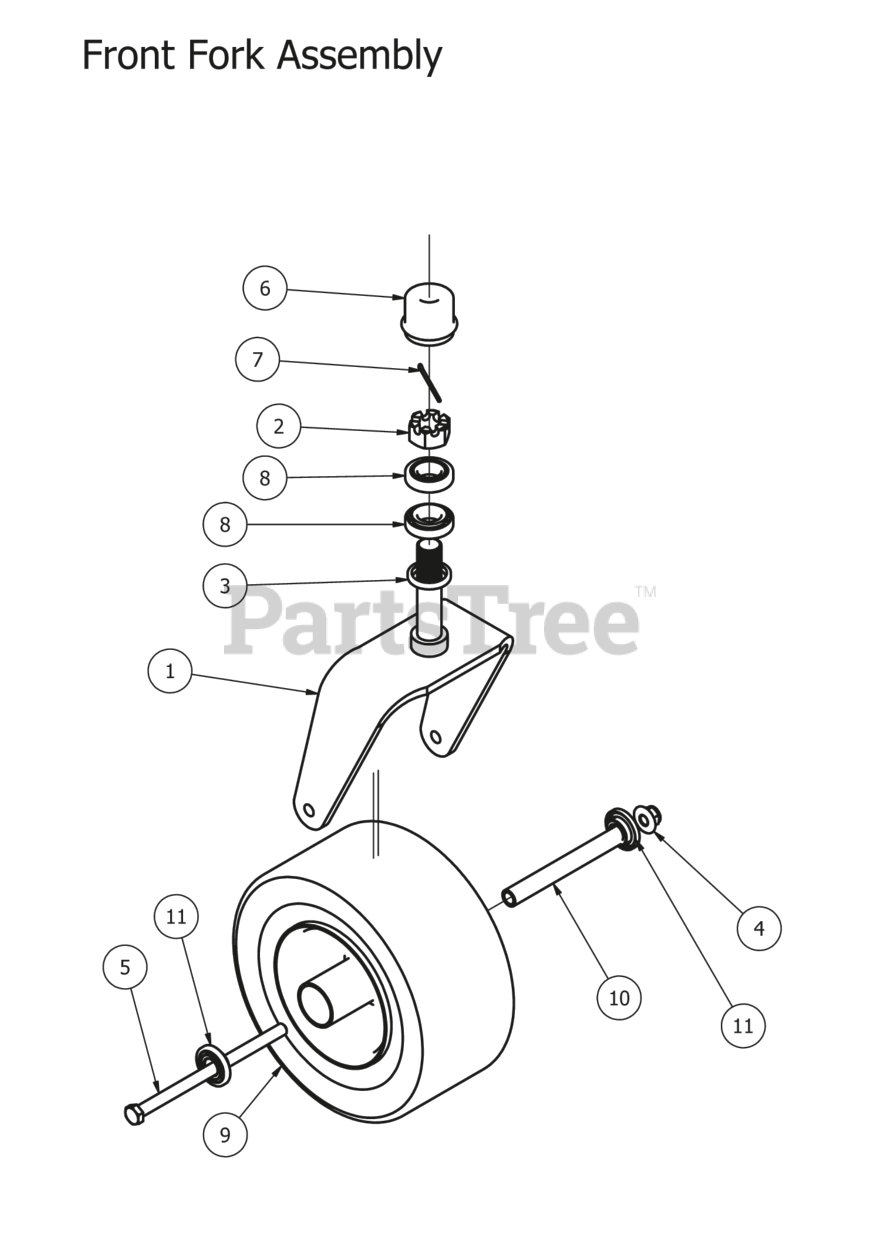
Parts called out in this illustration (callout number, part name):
1	Front Fork
2	1" Fine Threaded Castle Nut
4	1/2-13 Nylon Flange Nut-Orange
5	1/2" x 9" Bolt
6	Dust Cover
7	1/8x2-1/4 cotter pin Zinc
9	Tire and wheel assembly
10	Front Wheel Spacer
11	Wheel Bearing
